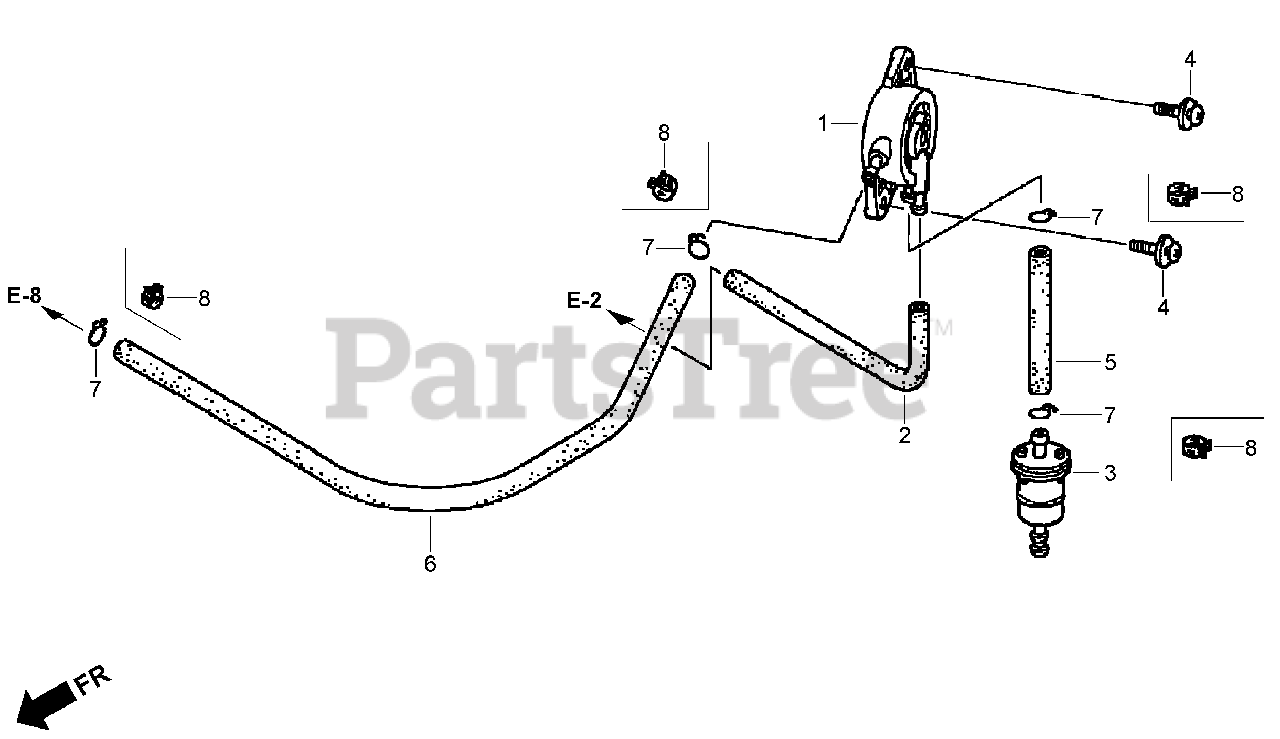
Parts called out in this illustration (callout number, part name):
1	FUEL PUMP ASM
2	TUBE-DIAPHRAGM
3	FILTER-FUEL
4	SCREW-WASHER (5X16)
5	TUBE-FUEL (5.3X100) (FKM) (From Engine Serial No. 1001842)
5	HOSE-FUEL, BULK (5.5X3000) (55X100) ( Up To Engine Serial No. 1001841)
6	TUBE-FUEL (5.3X350) (FKM) (From Engine Serial No. 1001842)
6	HOSE-FUEL, BULK (5.5X3000) (5.5X350) ( Up To Engine Serial No. 1001841)
7	CLIP-TUBE (B10) ( Up To Engine Serial No. 1001841)
8	CLAMP-TUBE (D10) (From Engine Serial No. 1001842)
